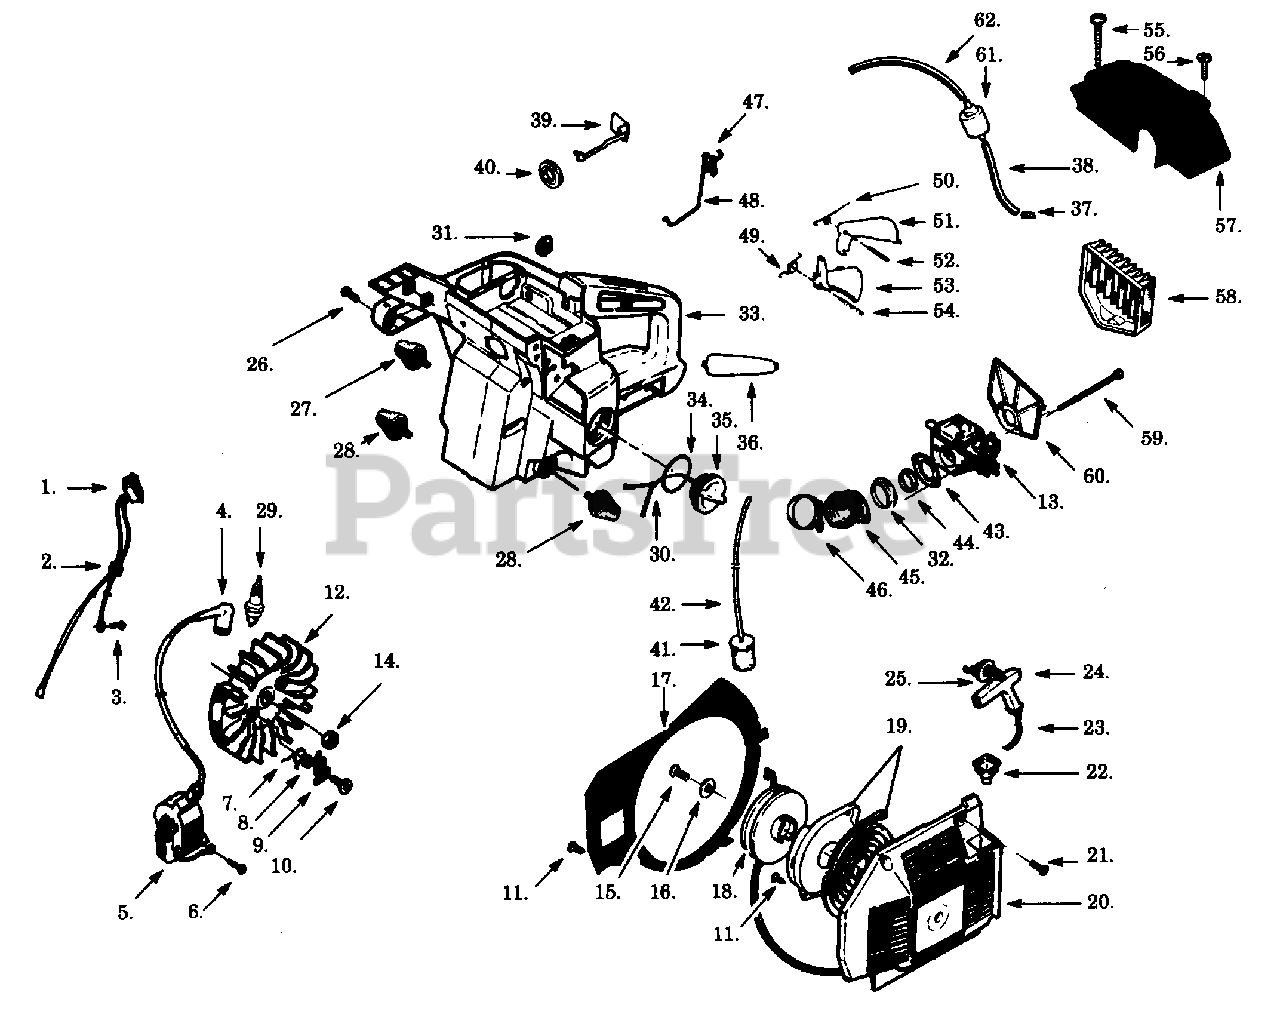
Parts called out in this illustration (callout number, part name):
1	Switch Ass'y.
4	Plug Boot
5	Model 425
5	Model 505
7	Starter Dog Spring
9	Starter Dog
12	Flywheel Ass'y (Incl. 7-10)
13	Carburetor
17	Air Baffle
18	Starter Pulley
19	Starter Spring
20	Fan Housing
27	Spring Isolator
28	Spring Isolator
29	Spark Plug
30	Oil Cap Retainer
31	Nut
32	Inner Ring
33	Tank & Handle Ass'y. (Includ. 31, 41, & 42)
35	Fuel Cap
38	Hose
39	Choke Knob
41	Fuel Filter
42	Fuel Line
43	Carburetor Gasket
44	Outer Sealing Ring
45	Manifold Tube
46	Clamp
48	Throttle Wire
51	Trigger Lock
57	Air Filter Cover
58	Std. Nylon Mesh
60	Air Filter Base Plate
61	Vent Valve
